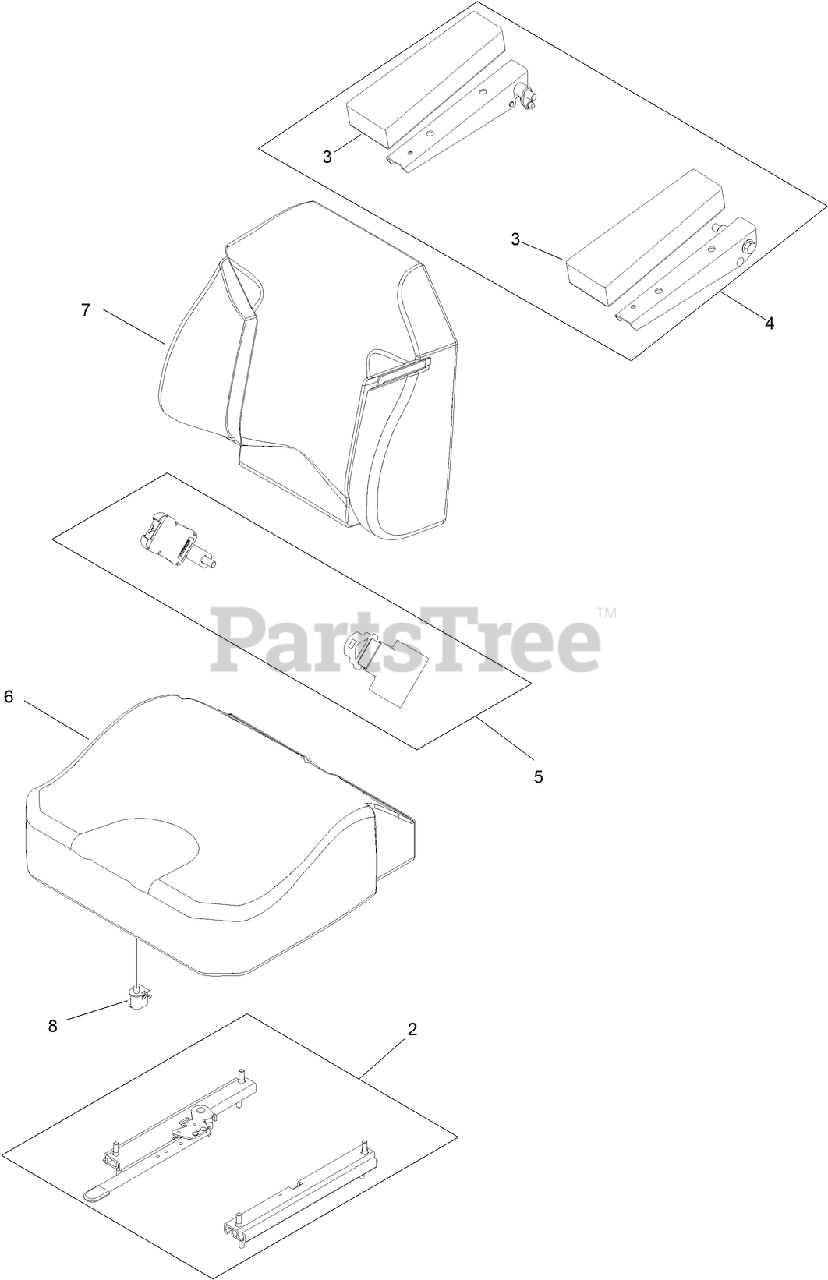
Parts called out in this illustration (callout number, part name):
2	SEAT TRACK SET
3	ARM REST PADS SET
4	ARM REST KIT
5	SEAT BELT KIT
6	COVER-CUSHION
7	COVER-BACK
8	SWITCH-BAIL
